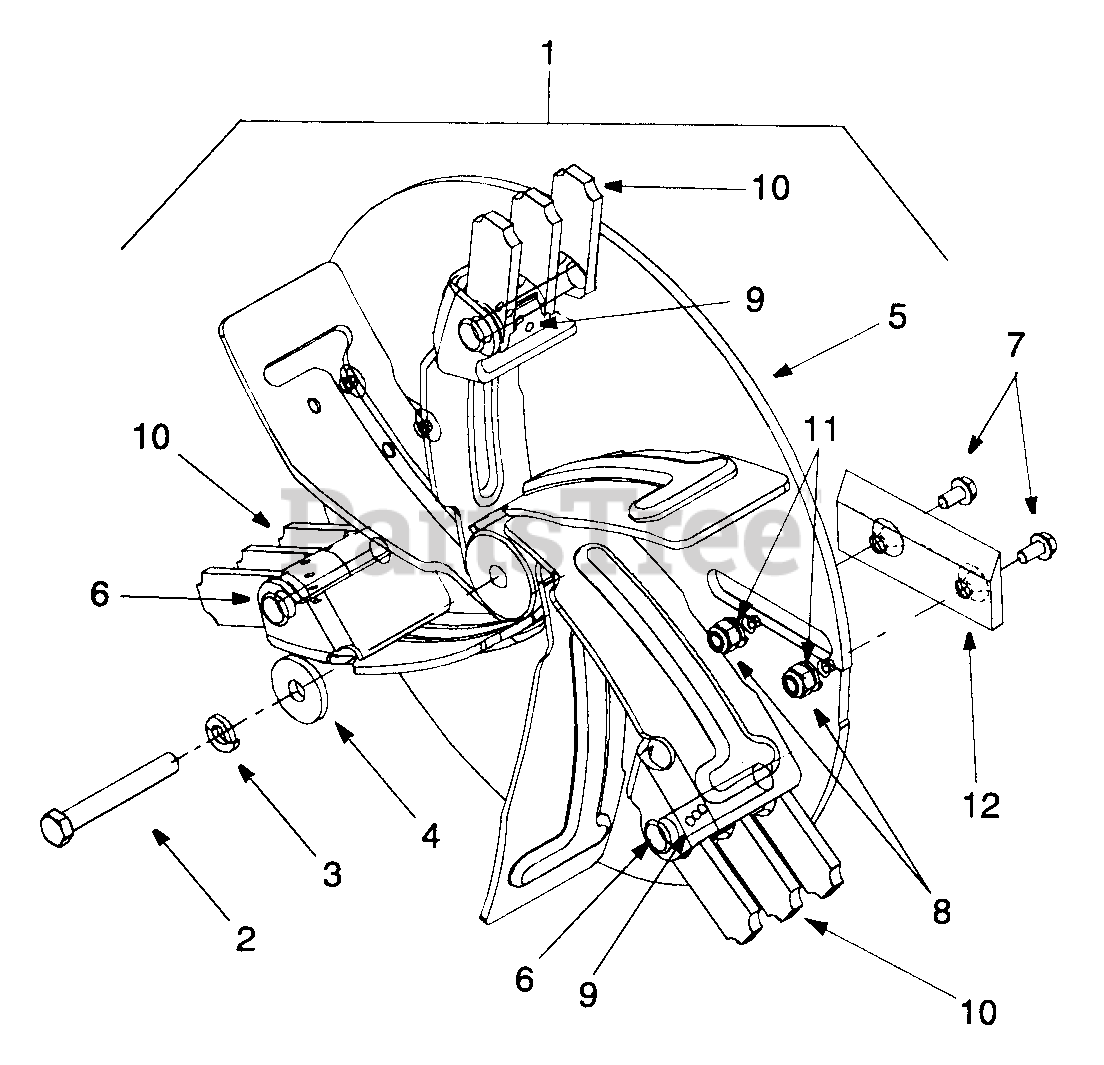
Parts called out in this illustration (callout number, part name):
1	Impeller Ass'y
2	Screw, Hex Cap, 3/8-24 x 2.75 GR5
3	Washer, Lock, 3/8 Heavy Duty
4	Washer, Flat, .406 x 1-1/4 HD
5	Impeller
6	Pin, Clevis
7	Screw, Flat Hd. Cap, 5/16-24 x 1.0
8	Nut, Hex Insert Lock, 5/16-24
9	Pin, Spirol,.156x1.000 Std.
10	Blade, Flail
11	Washer, Lock, 5/16
12	Blade, Chipper
